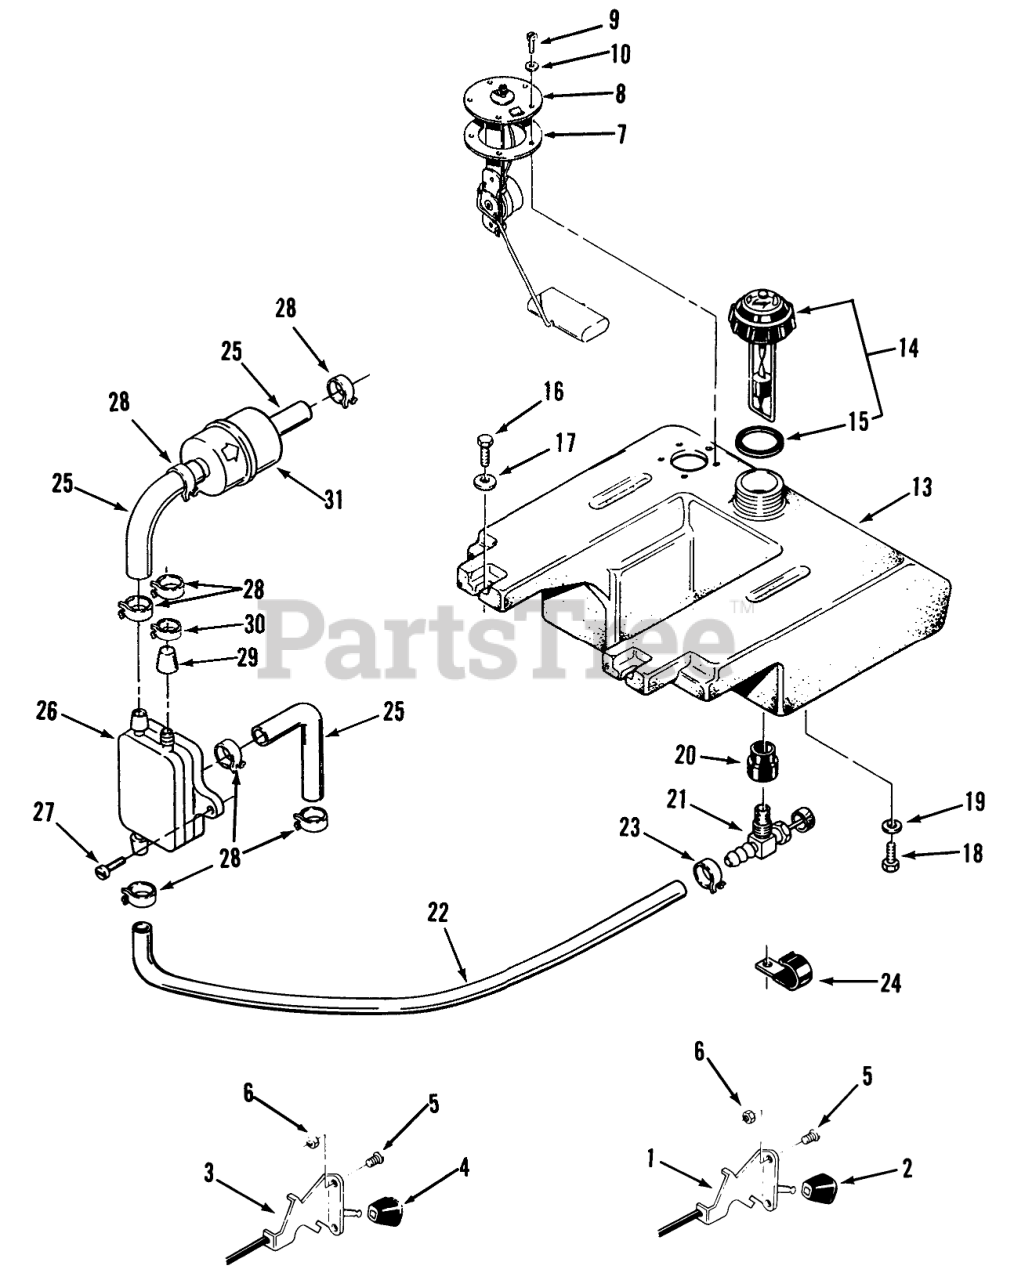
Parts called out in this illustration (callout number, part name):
1	CONTROL-THROTTLE
2	KNOB-CONTROL
3	CONTROL-CHOKE
4	KNOB-CONTROL
5	SCRW-PHC
6	Nut
7	GASKET-SENDER, FUEL
8	SENDER-FUEL LEVEL
9	Screw
10	Lockwasher
13	Fuel Tank (Includes items 20 & 21)
14	Fuel Cap (Includes item 15)
15	GASKET-GAS CAP
16	Bolt
17	Washer
18	Bolt
19	Lockwasher
20	BUSHING
21	VALVE-FUEL
22	Line-Fuel 53"
23	Clamp
24	Clamp
25	Hose
26	Fuel Pump
27	Screw
28	Clamp
29	Cap
30	Clamp
31	Filter-Fuel
